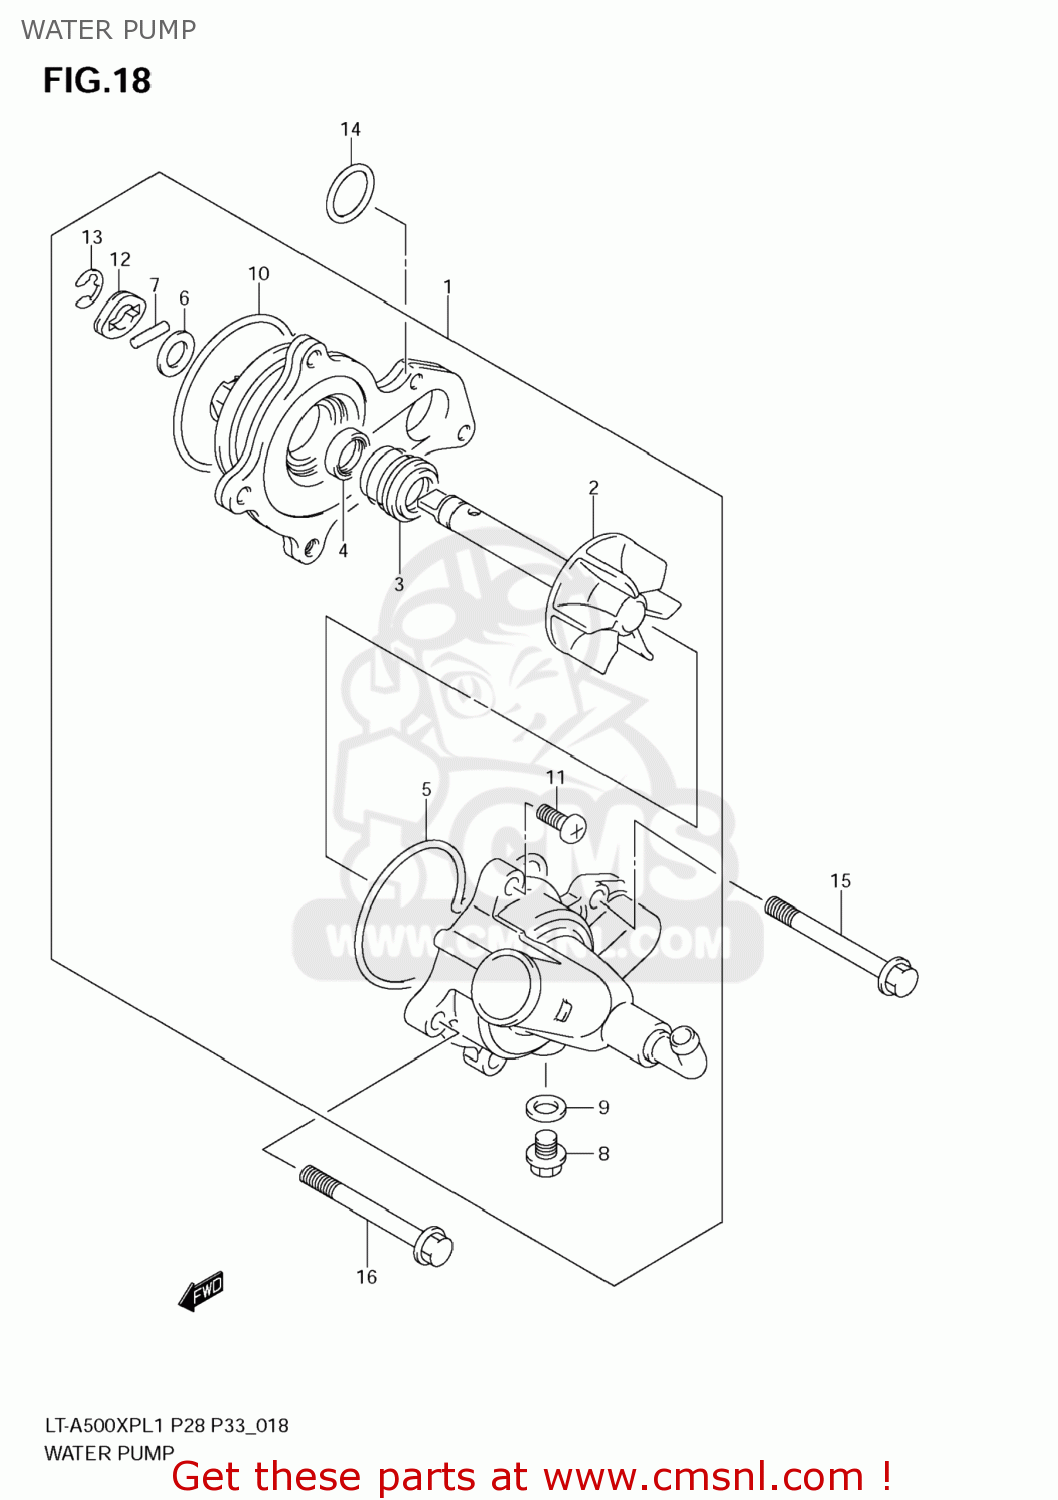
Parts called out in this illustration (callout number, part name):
1	PUMP ASSY,WATER
2	IMPELLER
3	SEAL,MECHANICAL
4	SEAL,OIL
5	O RING
6	WASHER
7	PIN
8	BOLT,DRAIN
9	GASKET(8.2X14X1) (NAS)
10	O RING,WATER PUMP HOLDER
11	SCREW
12	CAP
13	E RING
14	O RING(D:2.4,ID:21.8)
15	BOLT
16	BOLT
